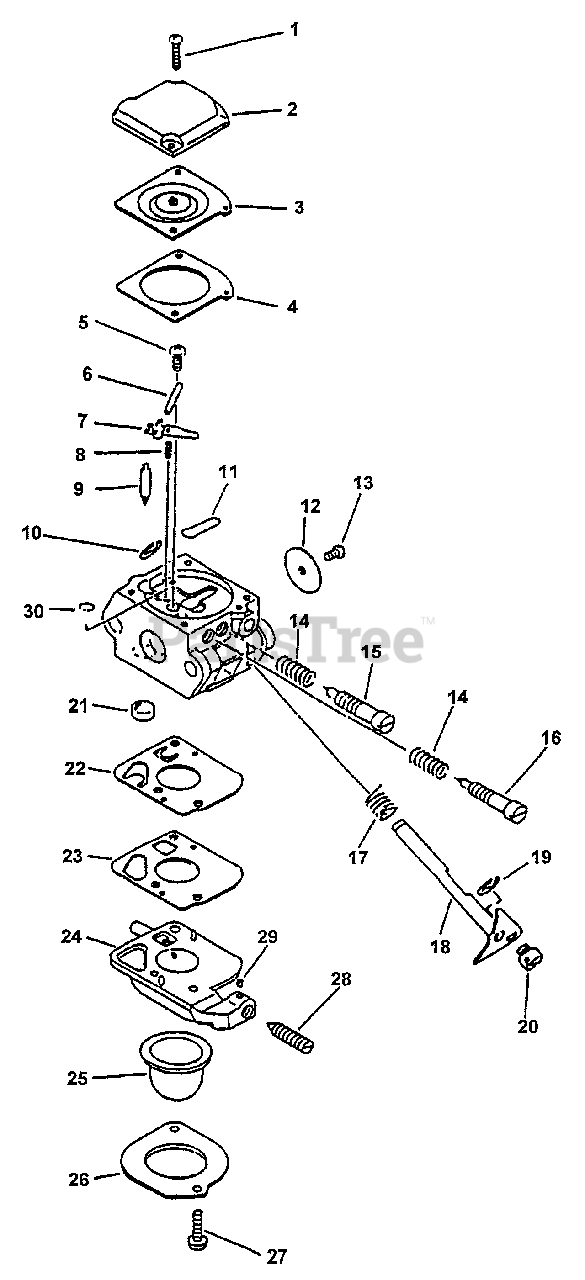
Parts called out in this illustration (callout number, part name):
2	COVER, METERING
3	DIAPHRAGM
4	GASKET, METERING
5	SCREW, METERING LEVER PIN
6	PIN, METERING LEVER
7	LEVER, METERING
8	SPRING
9	VALVE, INLET NEEDLE
10	RING, RETAINING
11	PLUG, WELCH
12	VALVE, THROTTLE
15	NEEDLE - HIGH SPEED
16	NEEDLE - MIXTURE
17	SPRING, RETURN
18	SHAFT, THROTTLE
19	RING, RETAINING
21	STRAINER
22	DIAPHRAGM, PURGE
23	GASKET, PURGE
24	BASE, PURGE
25	BULB, PURGE
26	RETAINER, PURGE BULB
27	SCREW, RETAINER
28	SCREW, IDLE ADJUST
29	PIECE, FRICTION
30	NOZZLE, CHECK VALVE
